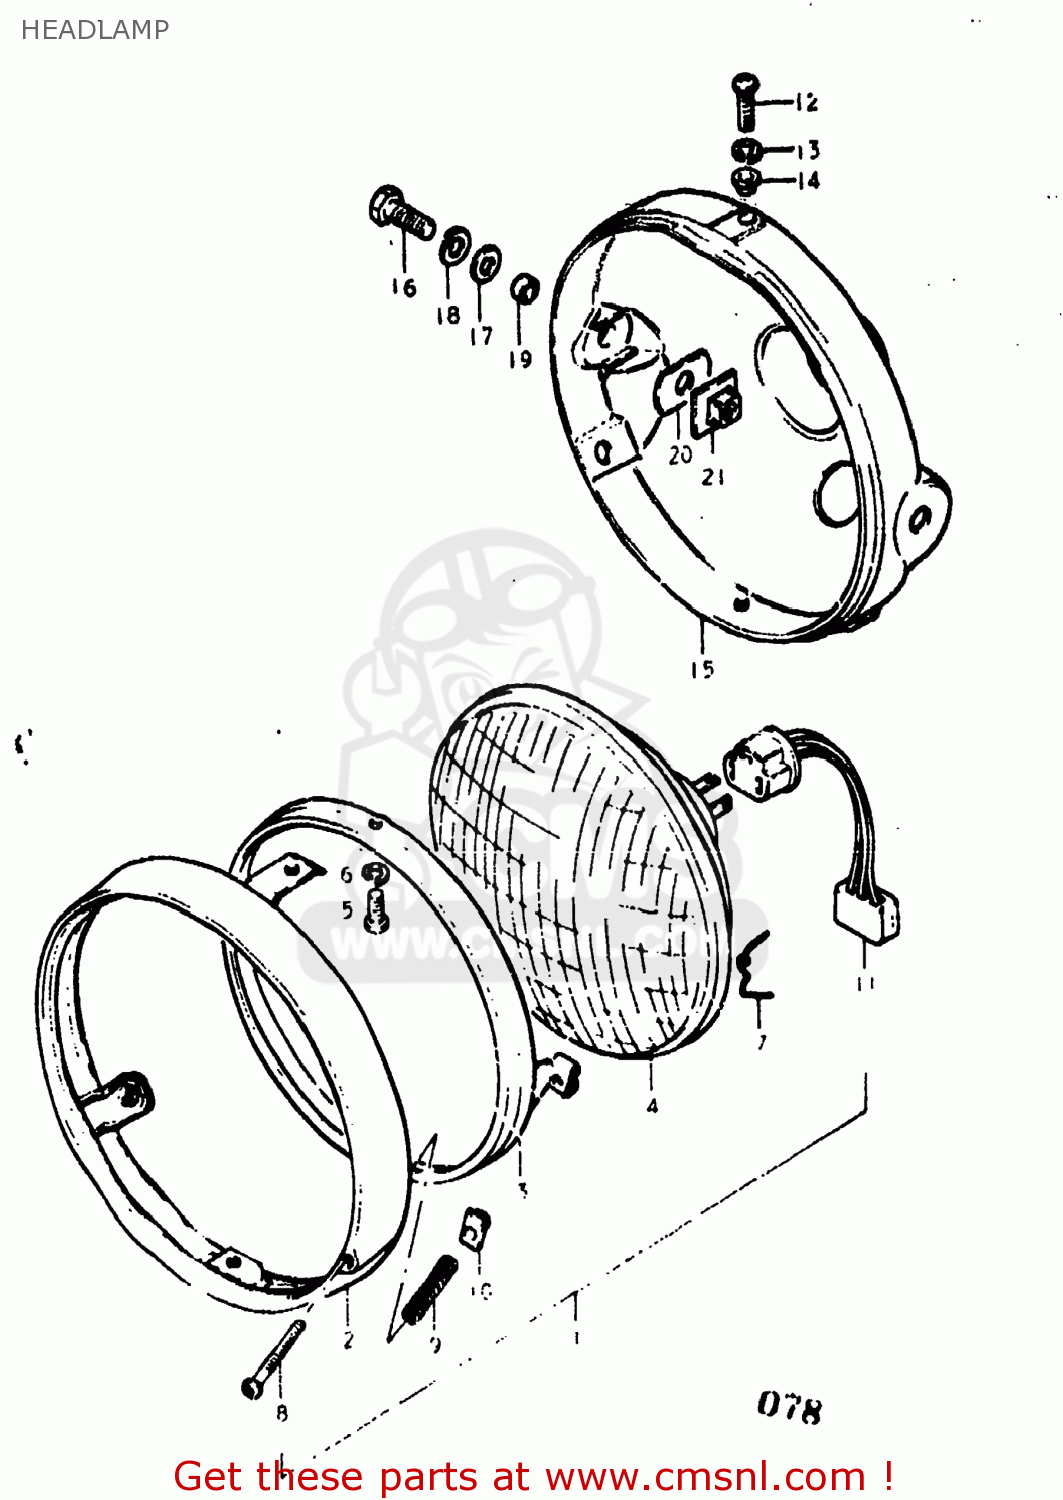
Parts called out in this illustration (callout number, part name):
1	HEADLAMP ASSEMBLY
2	RIM,HEADLAMP
3	RETAINER,HEADLAMP
4	LAMP UNIT
5	SCREW
6	LOCK WASHER
7	SPRING
8	SCREW,HEADLAMP ADJUST
9	SPRING
10	NUT
11	LEAD WIRE,HEADLAMP
12	SCREW
13	WASHER,LOCK
14	WASHER
15	HOUSING,HEADLAMP(BLACK)
16	BOLT
17	WASHER
18	LOCK WASHER
19	SPACER (8.8X12X7)
20	CUSHION
21	PLATE,HEADLAMP HOUSING
